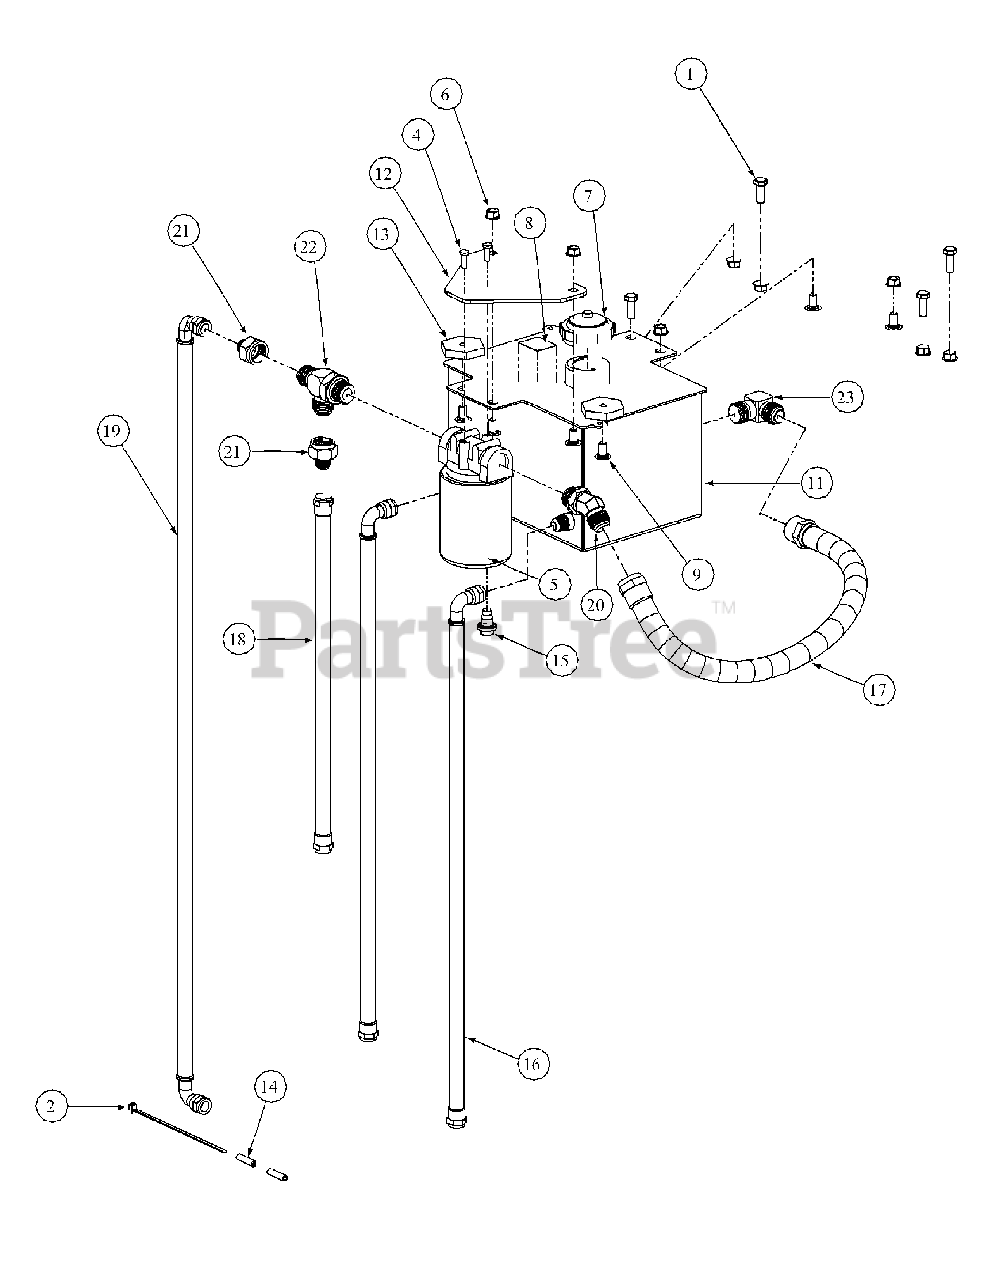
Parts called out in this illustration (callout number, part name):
1	Hex Cap Screw, 3/8-16, 1
2	Cable Tie, 3/16 x .05 x 7.4
3	Sleeve, Reel Return Line
4	Hex Cap Screw, 1/4-20, .75
5	Filter Head 3/4
5	33 Micron Filter
6	Hex Nut Flange Lock, 3/8-16
7	Cap, Hydro Oil Tank
8	Decal Oil Only 20W50
9	Carriage Bolt, 3/8-16 x .75 LG.
11	Hydraulic Tank Assembly
12	Mounting Plate Oil Filter
13	Spacer, 2.000 Hex x .41 LG
14	Set Screw, 5/16-24 x 1.25
15	Oil Pan Drain w/ Seal and Plug
16	Gearbox to Tank Hose Assembly
17	Tank to Filter Hose Assembly
18	Filter to Left Hand Pump Hose Assembly
19	Filter to Right Hand Pump Hose Assembly
20	Connector, 3/4 x3/4
21	Adapter 3/4 x 1/2
22	Fitting Tee, 3/4 x 3/4 x 3/4
23	Fitting Elbow, 1/2 x 1/2
